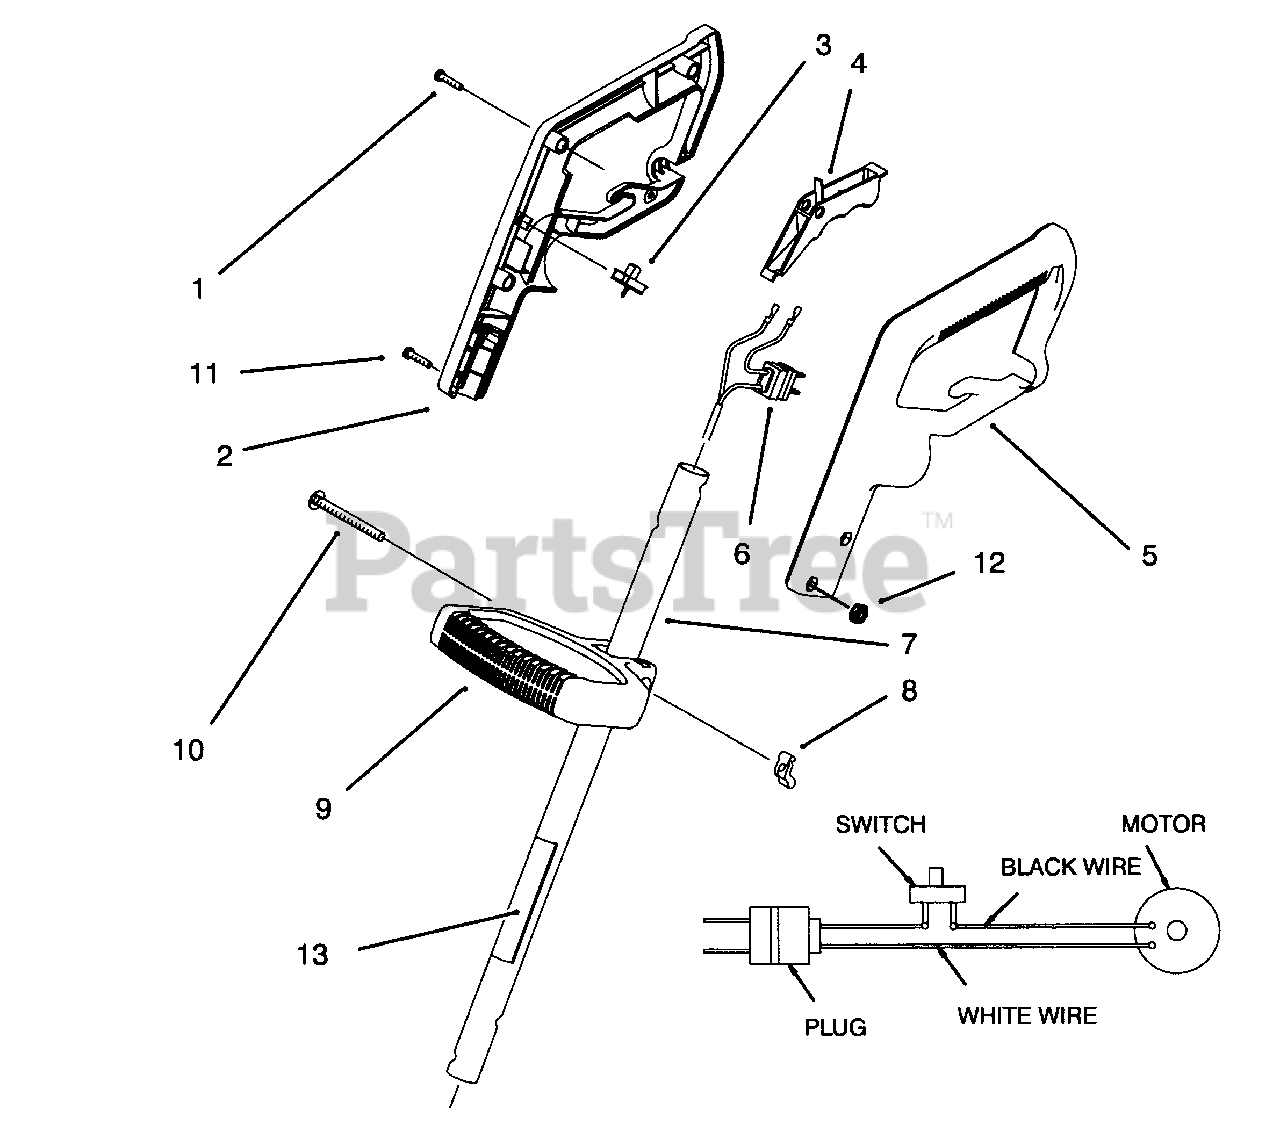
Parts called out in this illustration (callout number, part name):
1	Screw-Pan Hd Tapping
2	Grip-Hand R.H.
3	Switch-Single Speed
5	Grip-Hand L.H.
6	Harness-Wire
7	Tube Assembly (Incl. Ref. #13)
9	Handle-Mid
10	Screw-Carriage
11	Screw-Pan Hd.
12	Nut-Lock
13	Decal-Safety
